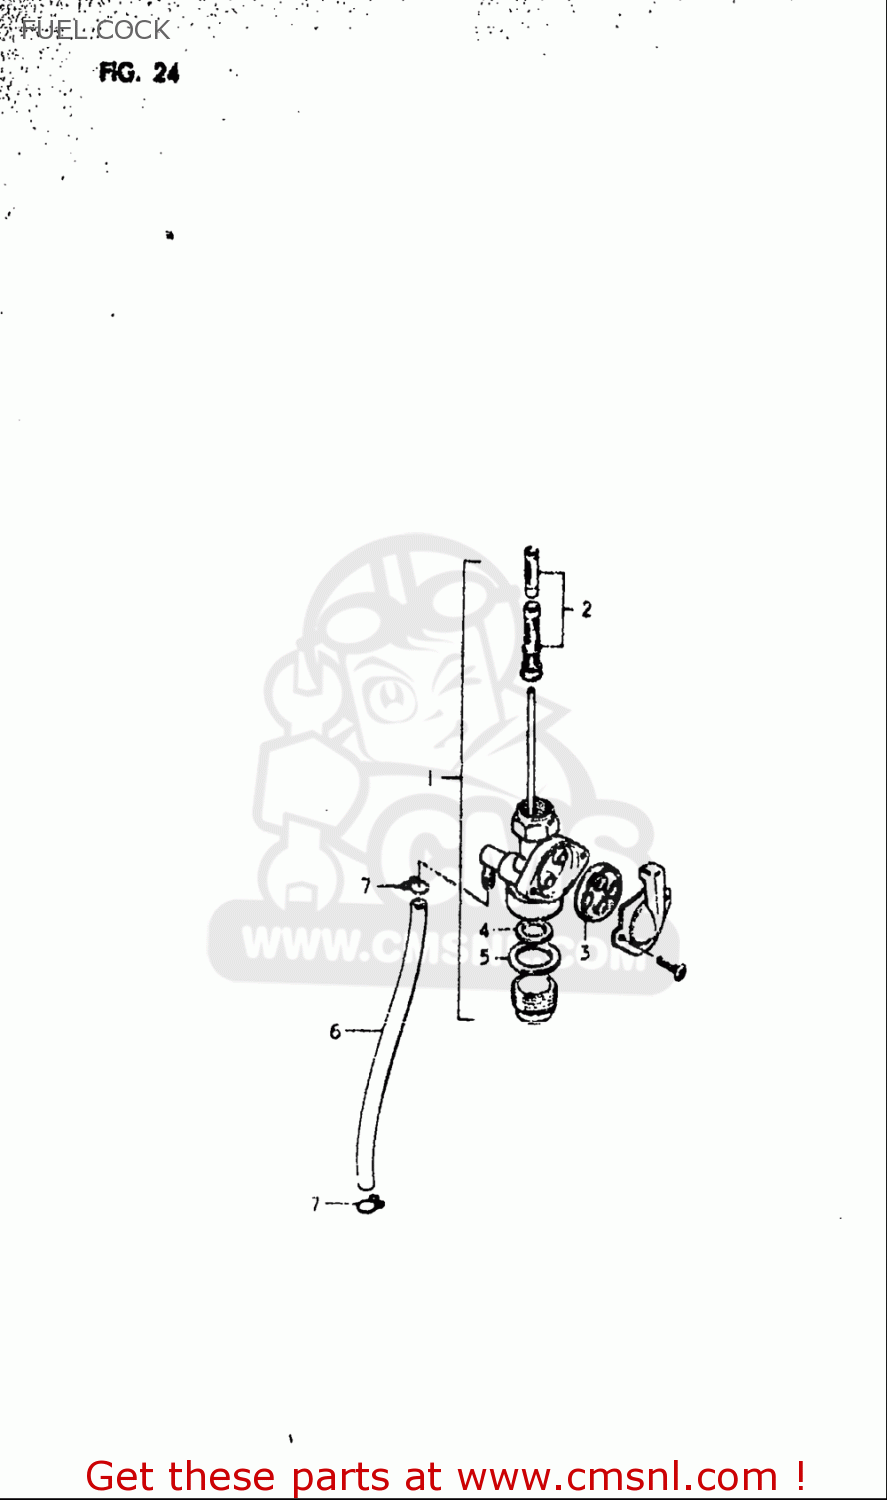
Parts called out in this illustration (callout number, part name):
1	COCK ASSY,FUEL
2	FILTER SET,FUEL
3	GASKET,LEVER (NAS)
4	NET,STRAINER
5	GASKET,STRAINER CUP (NAS)
6	HOSE(5X8.2X600)
7	CLIP
